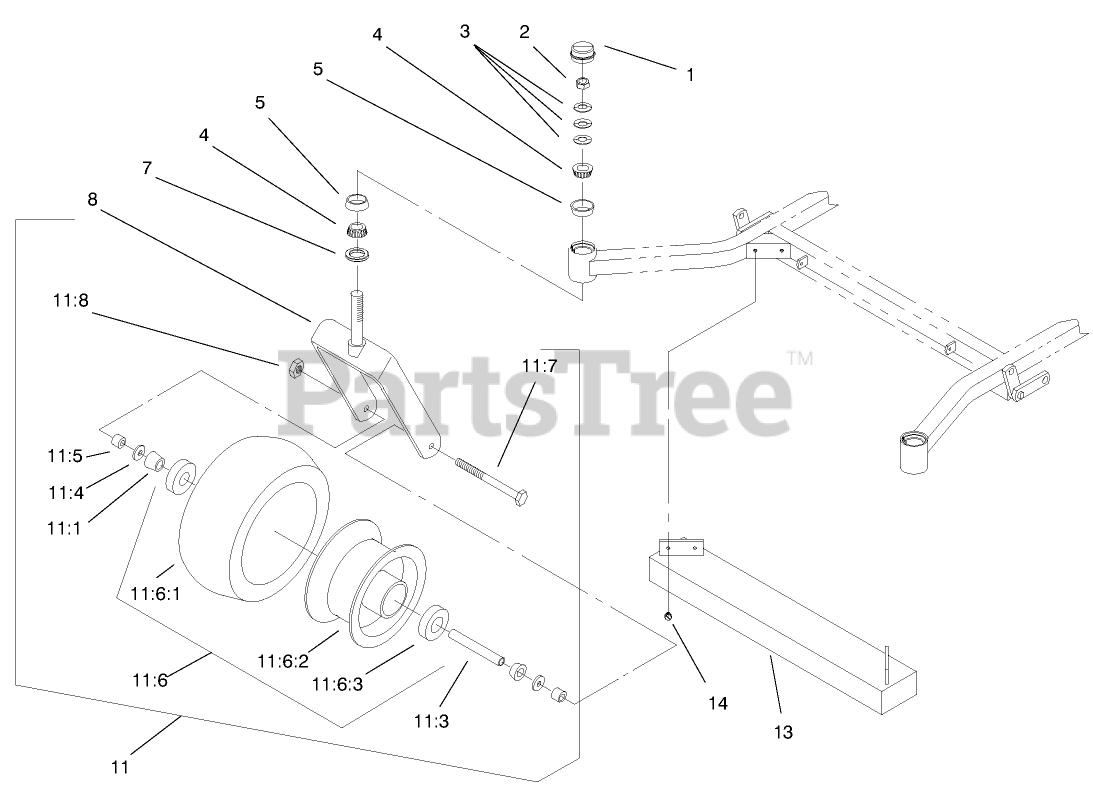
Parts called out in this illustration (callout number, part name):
1	Cap-Grease
2	LOCKNUT
3	Washer-Bellevue
4	BEARING-CONE, TAPERED
5	BEARING-CUP, TAPERED
7	Seal-Grease
8	Caster
11	Caster Wheel ASM
11:1	BEARING-CONE
11:3	Spacer
11:4	Seal-Bearing
11:5	Spacer-Bearing
11:6	Wheel & Tire ASM
11:6:1	Tire
11:6:2	Wheel
11:6:3	BEARING-ROLLER, CUP
11:7	SCREW-HH
11:8	NUT-LOCK, NI
13	Weight
14	SCREW-HWHTF
